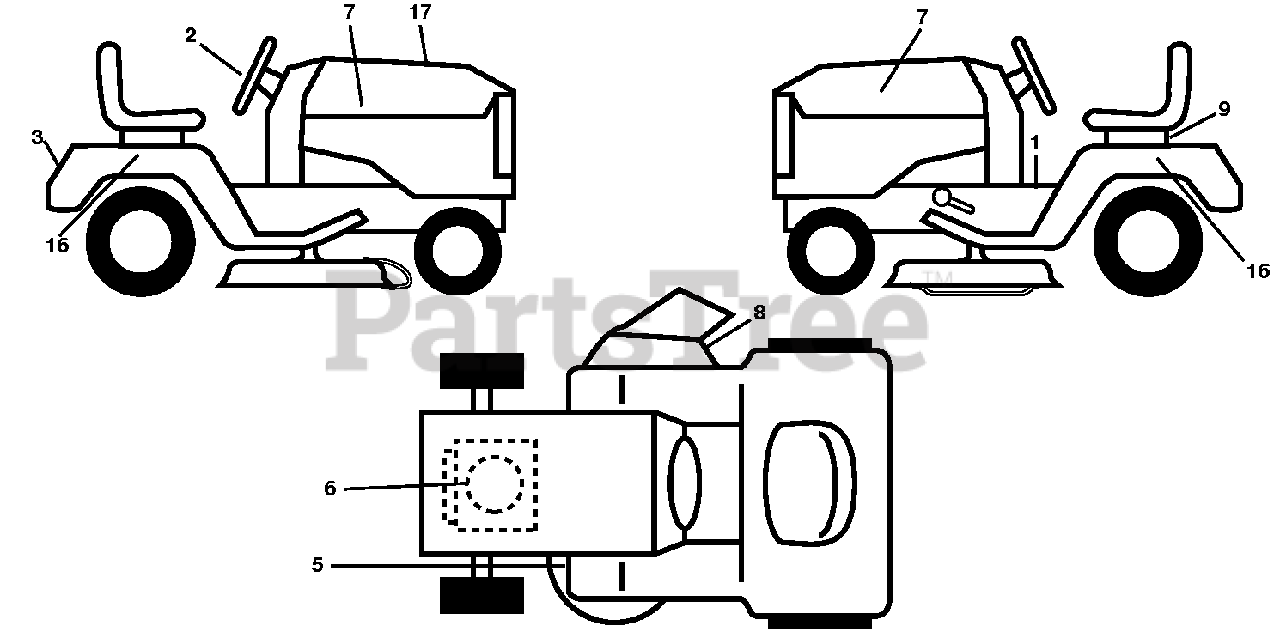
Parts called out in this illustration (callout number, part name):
1	DECAL.FENDER.WARNING.ENGLISH
2	DECAL.STEER.WHEEL.POULAN.PRO
3	DECAL.REAR.FNDR.LOGO.POULAN.PR
5	DECAL.V-BELT.SCH.42/46"MEC/ELE
6	DECAL.ENG.BS.18INTK.DOM.381706
7	DECALS HOOD PANELS
8	DECAL.MOWER.WARN.KEEP.HAND.AWY
9	DECAL BTRY SYMBOLS
17	Decal, Replacement BSM40 TLW 46 GENTRL
